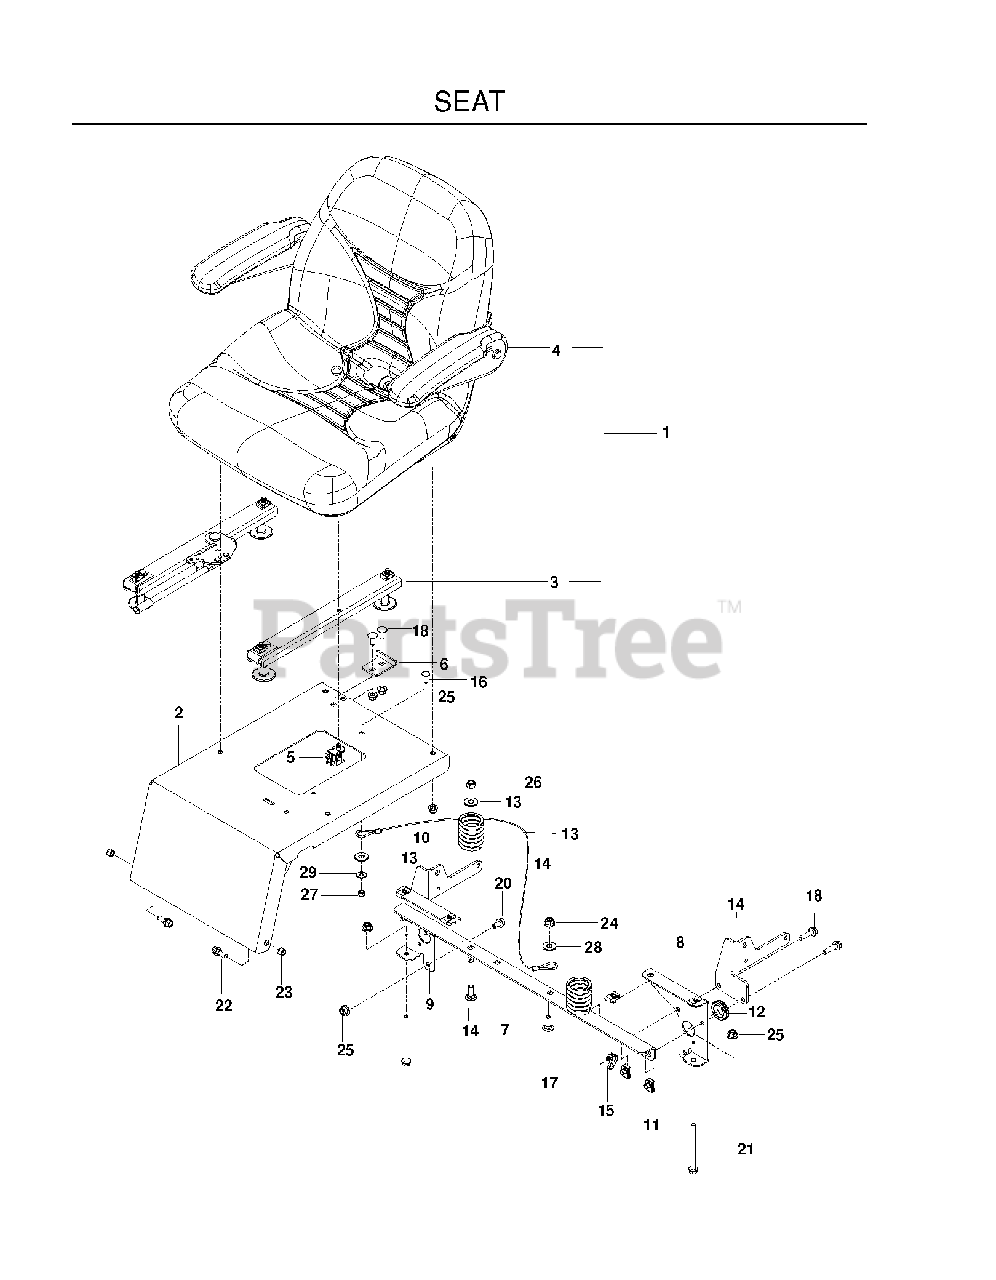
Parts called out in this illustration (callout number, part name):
1	SEAT
2	KIT.SEAT.MOUNT.W/DECAL
3	TRACK ADJUSTMENT KIT
4	ARMREST KIT, LT SQUARE END
5	SWITCH.SNAPMOUNT.NC
6	STOP, SEAT - BLACK
7	SUPPORT, SEAT
8	SUPPORT, LT, BLK
9	SUPPORT, RT, BLK
10	SPRING, SEAT
11	U-CLIP 5/16-18 NUT RETAINER
12	RUBBER GROMMET
13	SEAT LANYARD
14	MOUNT, SEAT BELT, BLACK
15	TIE WRAP, 8-3/8", W/CLIP
16	RHSNB 1/4C X 3/4
17	RHSNB 3/8C X 1
18	RHSNB 5/16-18 X 3/4
20	HHFS 5/16-18 X 3/4
21	HHFS 5/16-18 X 3 3/4
22	SB 5/16-18 HEX HD GD5, BLK ZN
23	NUT 5/16 NYLOC
24	NUT 3/8-16 HEX FLG NYLOC ZD
25	5/16-18 NYLOC FLANGE NUT
26	NUT 3/8-16 NYLOC
27	RP_NUT 1/4-20 NYLOC
28	RP WASHER 3/8 FLAT
29	WASHER 1/4 FLAT
